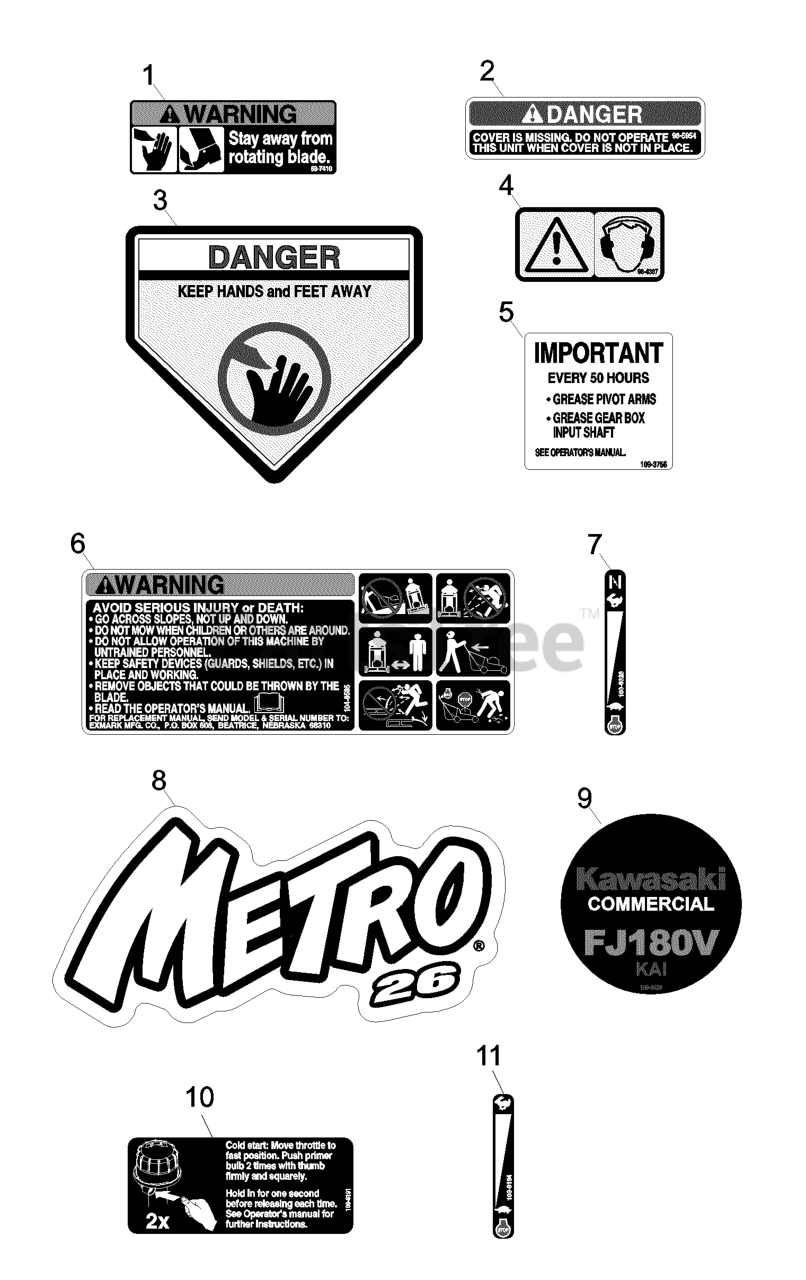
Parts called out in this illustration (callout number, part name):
1	DECAL-BLADE
2	DECAL-COVER, MISSING
3	DECAL-DANGER
4	DECAL-PROTECTION, EAR
5	DECAL,SERVICE M26
6	DECAL-WARNING
7	DECAL-THROTTLE / CHOKE
8	DECAL,METRO 26
10	DECAL, PRIMER
11	BOLT-HANDLE
